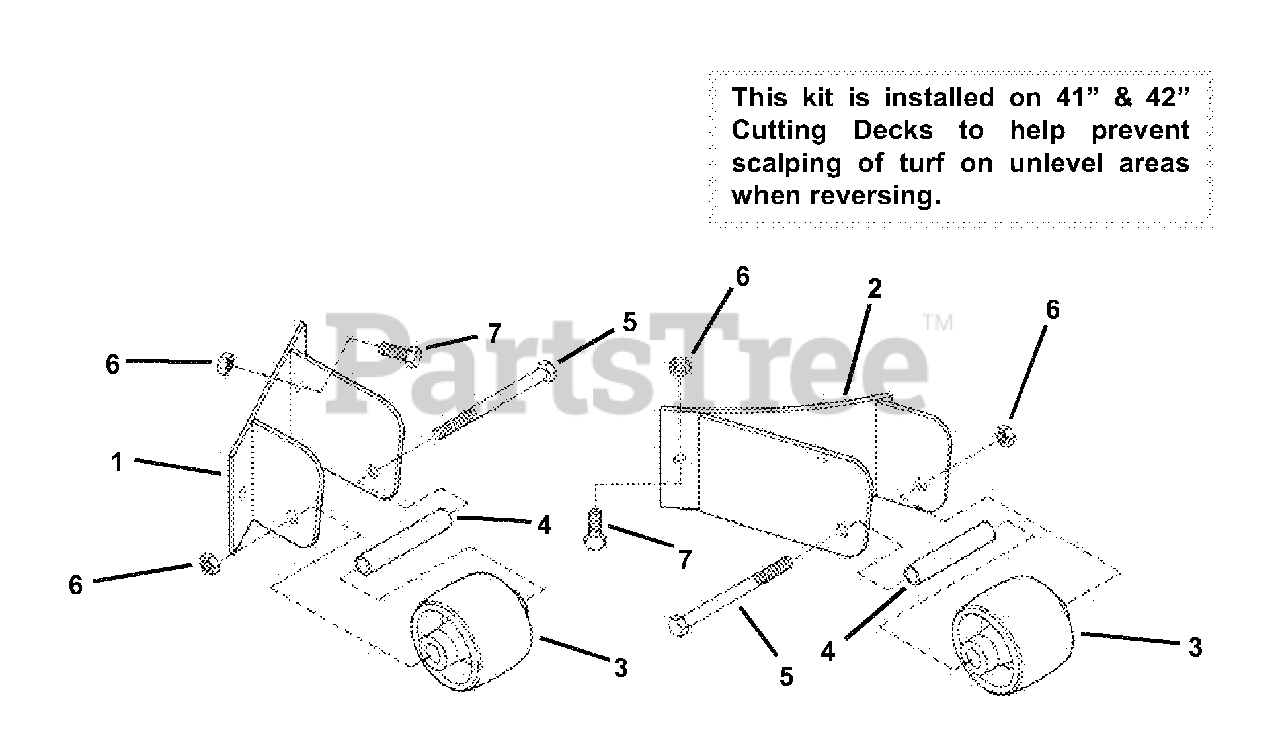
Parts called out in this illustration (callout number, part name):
1	BRACKET, Right Hand
2	BRACKET, Left Hand
3	WHEEL
4	SPACER, 3" Long
5	SCREW, 3/8-24 x 3-3/4" HHC
6	NUT, 3/8-24 Hex Center Lock
7	SCREW, 3/8-24 x 3/4"
